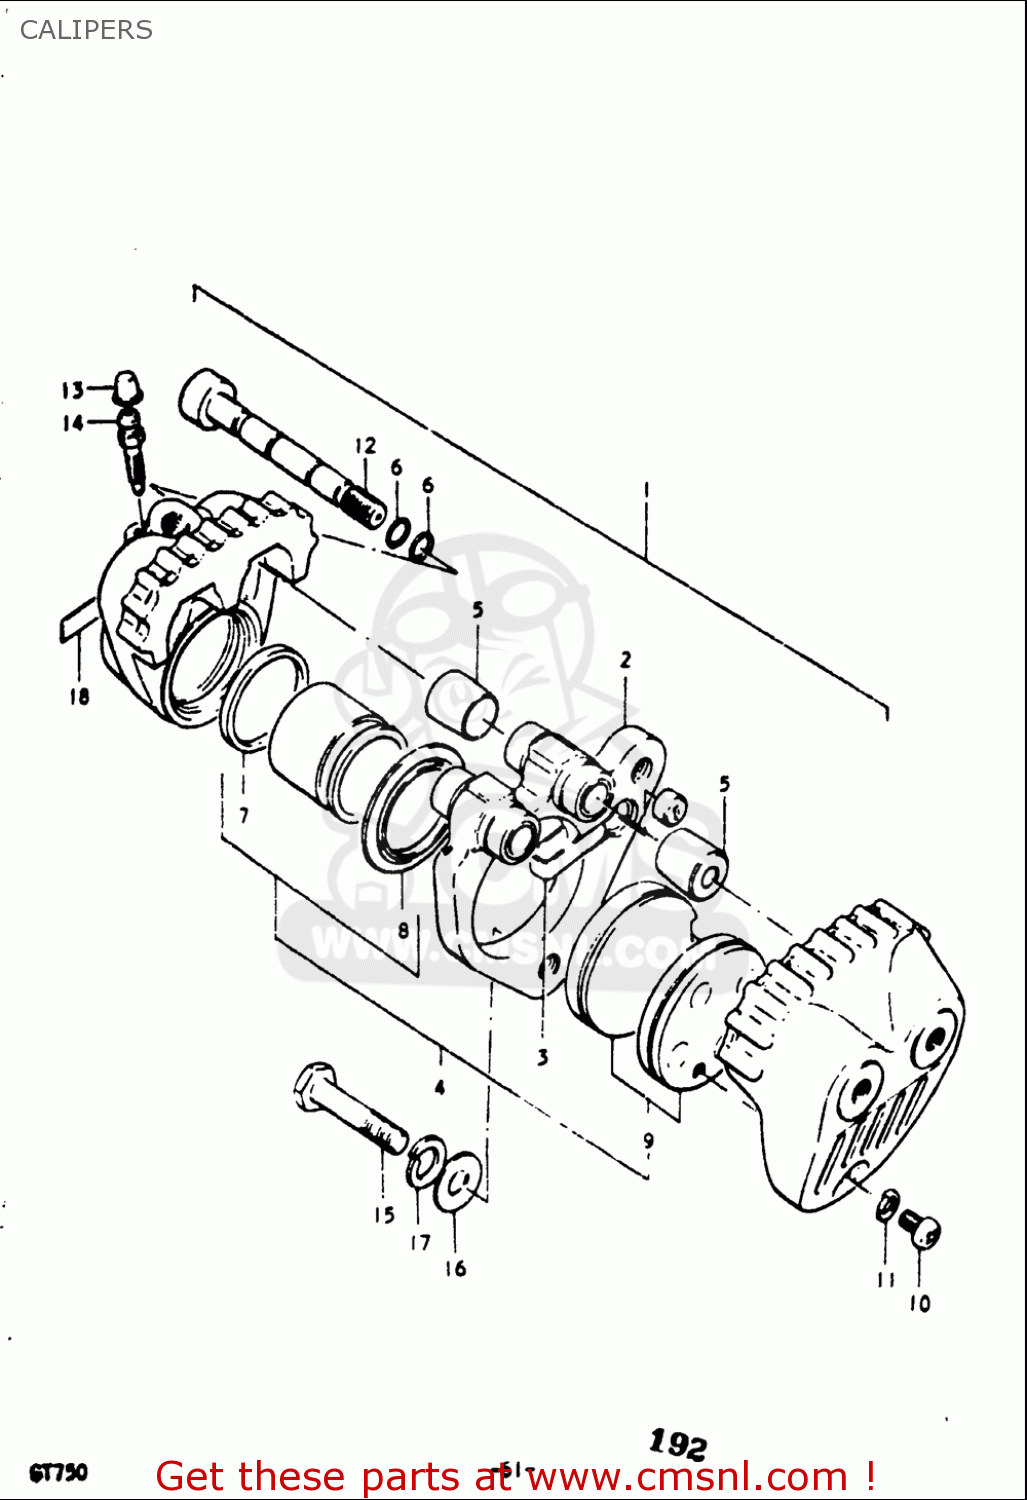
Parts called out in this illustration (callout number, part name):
4	PISTON SET
5	COVER,AXLE DUST
6	O RING,CALIPER AXLE
7	SEAL,PISTON
8	BOOT,PISTON
9	PAD SET (NAS)
10	SCREW
11	WASHER,LOCK
12	AXLE,CALIPER
13	CAP,BLEEDER PLUG
14	BLEEDER
15	BOLT(10X38)
16	WASHER
17	WASHER,LOCK
